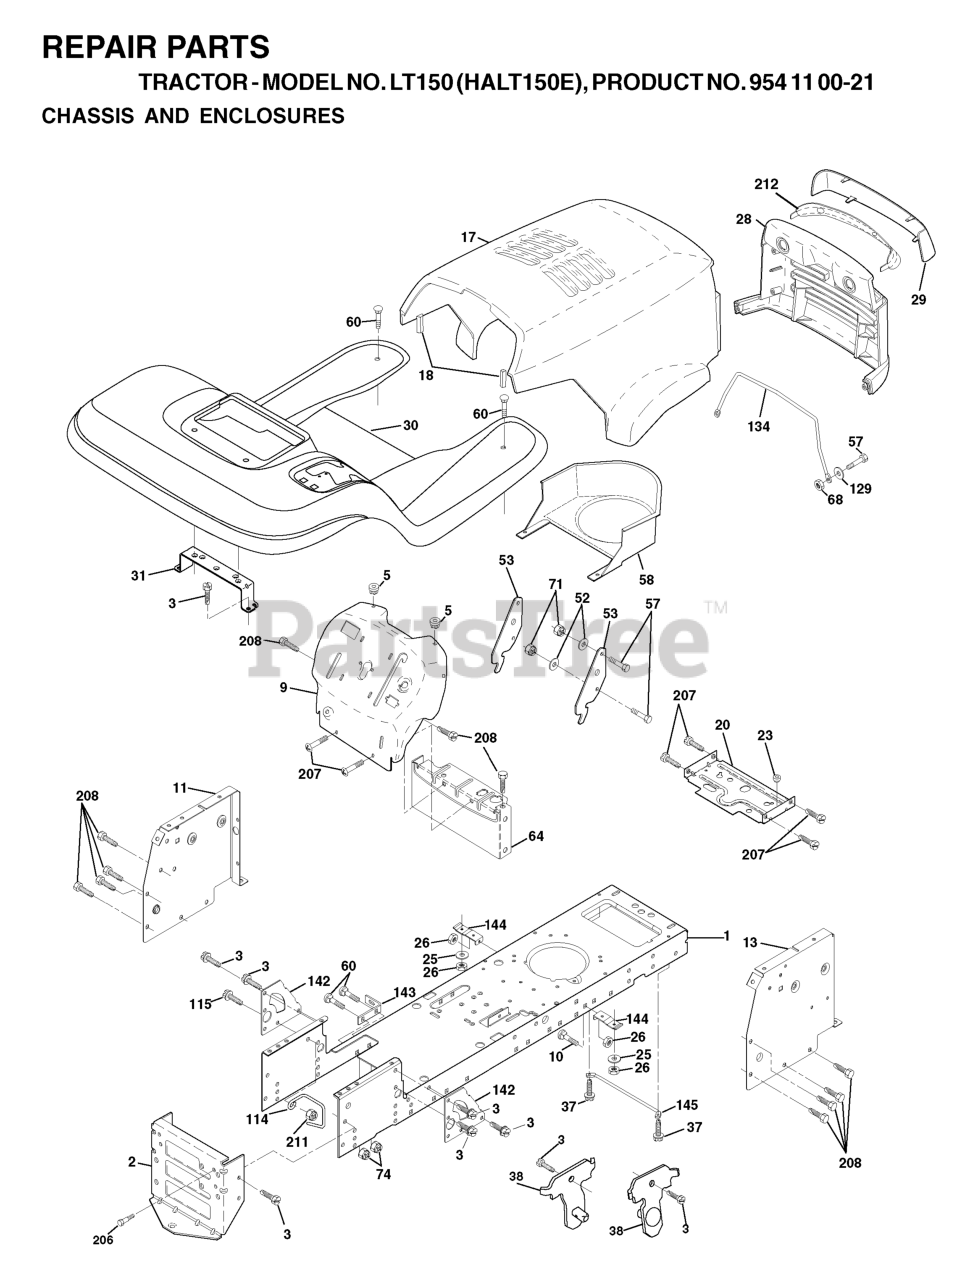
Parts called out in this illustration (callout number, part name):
2	DRAWBAR
3	SCREW 3/8-16X3/4
5	BUMPER.RUBBER.HOOD
9	DASH SILKSCR.
10	BOLT D
11	PANEL DASH LH
13	DASH PANEL RH
17	HOOD
18	BUMPER HOOD T
20	PLATE MTG
23	BUSHING.SNAP.NYL.BLK.
25	WASHER
26	NUT
28	GRILL
29	LENS
30	FENDER FOOTREST
31	BRACKET.SUPPORT.FENDER
37	Screw 5/16-18 x 1/2 Hex, Self Tapping 5/16-18 x 1/2
38	BRACKET
51	LOCKNUT.NYLOC.1/4-20
53	BRACKET PNT PICK OFF LT/PL
57	BOLT
58	AIR DUCT P/L/LT
60	Bolt - Rd. Hd. Sq. Neckiage 3/8 16 x 3/4
64	DASH LOWER
68	NUT
71	NUT.CROWNLOCK.1/4
114	BELT GUIDE
115	SCREW.3/8-16
134	ROD SUPPORT HOOD LT/PL HUS.
142	PLATE
143	BRACKET, SWAY BAR
144	BRACKET FOOTREST
145	ROD PIVOT CHASSIS/HOOD
206	SHOULDER BOLT 5/16-18TT
207	SCREW, 5/16-18 X 1/2
208	SCREW 3/8-16X1/2
211	NUT
